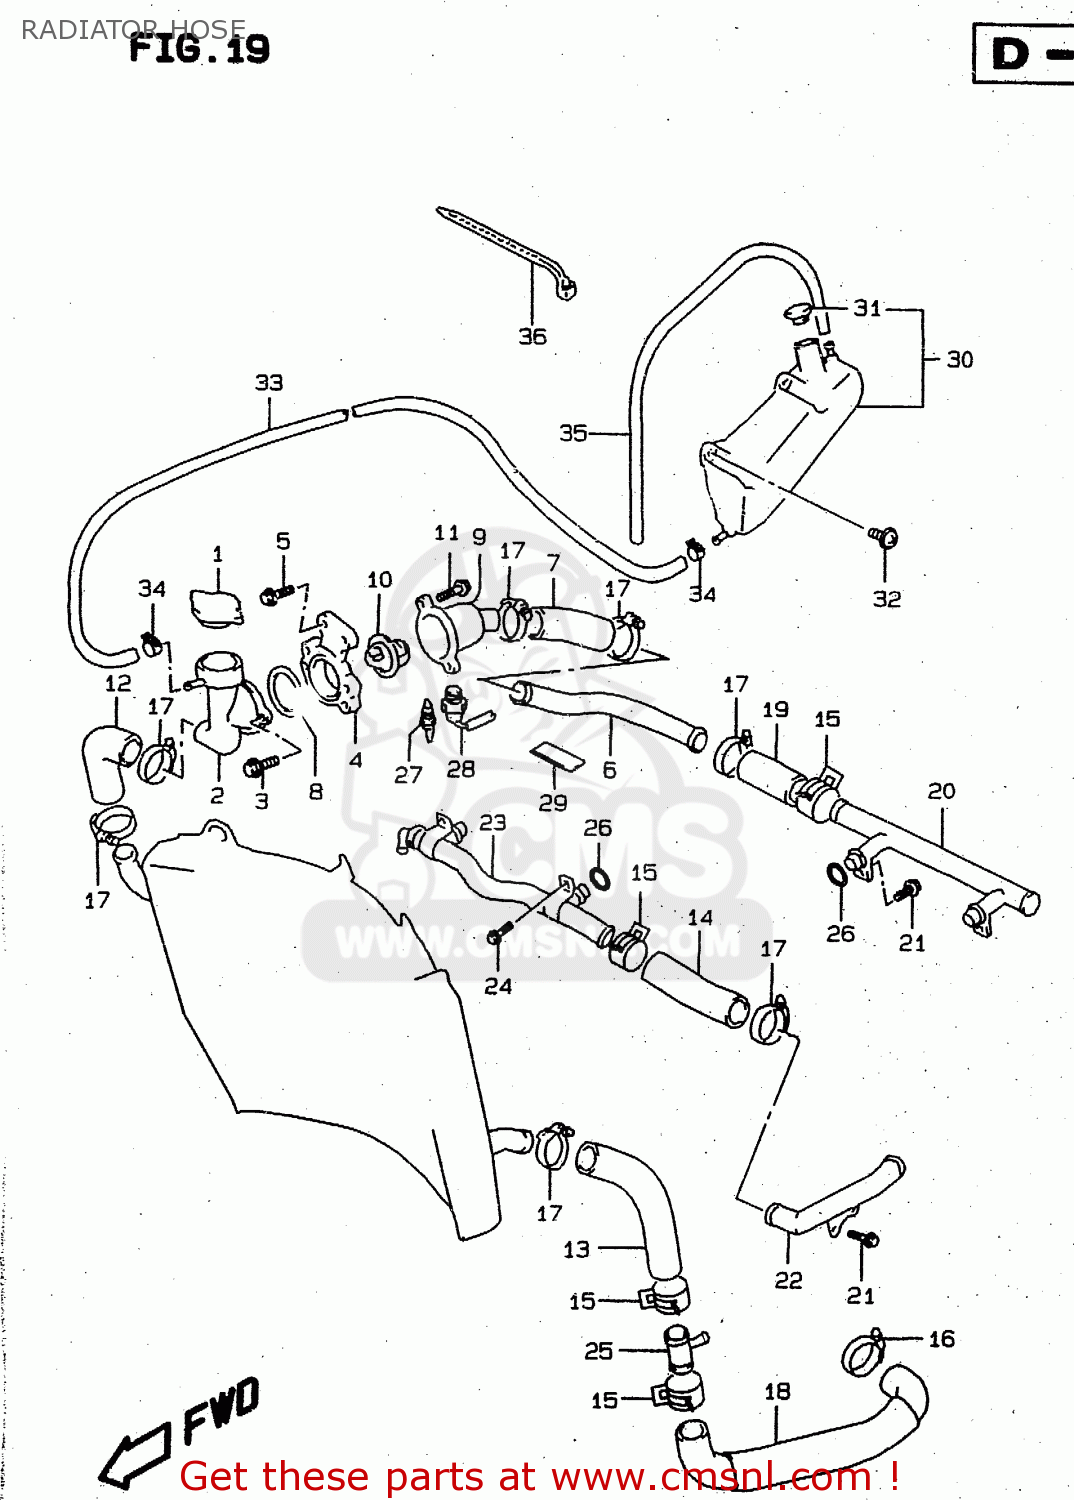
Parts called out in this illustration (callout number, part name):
1	CAP,RADIATOR
2	CONDUCTION,RADIATOR
3	BOLT
4	BRACKET,CONDUCTION
5	BOLT
6	PIPE,CONDUCTION INLET
7	HOSE,RADIATOR JOINT
8	O RING(D:2.4,ID:43.2)
9	CONNECTOR,THERMOSTAT INLET
10	THERMOSTAT,WATER
11	BOLT
12	HOSE,RADIATOR INLET
13	HOSE,RADIATOR OUTLET
14	HOSE,RADIATOR JOINT
15	CLAMP
16	CLAMP
17	CLAMP
18	HOSE,WATER PUMP INLET
19	HOSE,HEAD OUTLET
20	PIPE,HEAD OUTLET
21	BOLT
22	PIPE,CYLINDER SIDE
23	PIPE COMP,CYLINDER INLET
24	BOLT 6X12
25	UNION,HOSE JOINT
26	O RING(D:3.2,ID:17.8)
27	GAUGE ASSY,WATER TEMP
28	SWITCH,RADIATOR FAN
29	CUSHION(50X42X2.0)
30	TANK ASSEMBLY,RESERVOIR
31	CAP,RESERVOIR TANK
32	SCREW(6X20)
33	HOSE,RESERVOIR TANK
34	CLIP
35	HOSE,RESERVOIR TANK
36	CLAMP L:165
